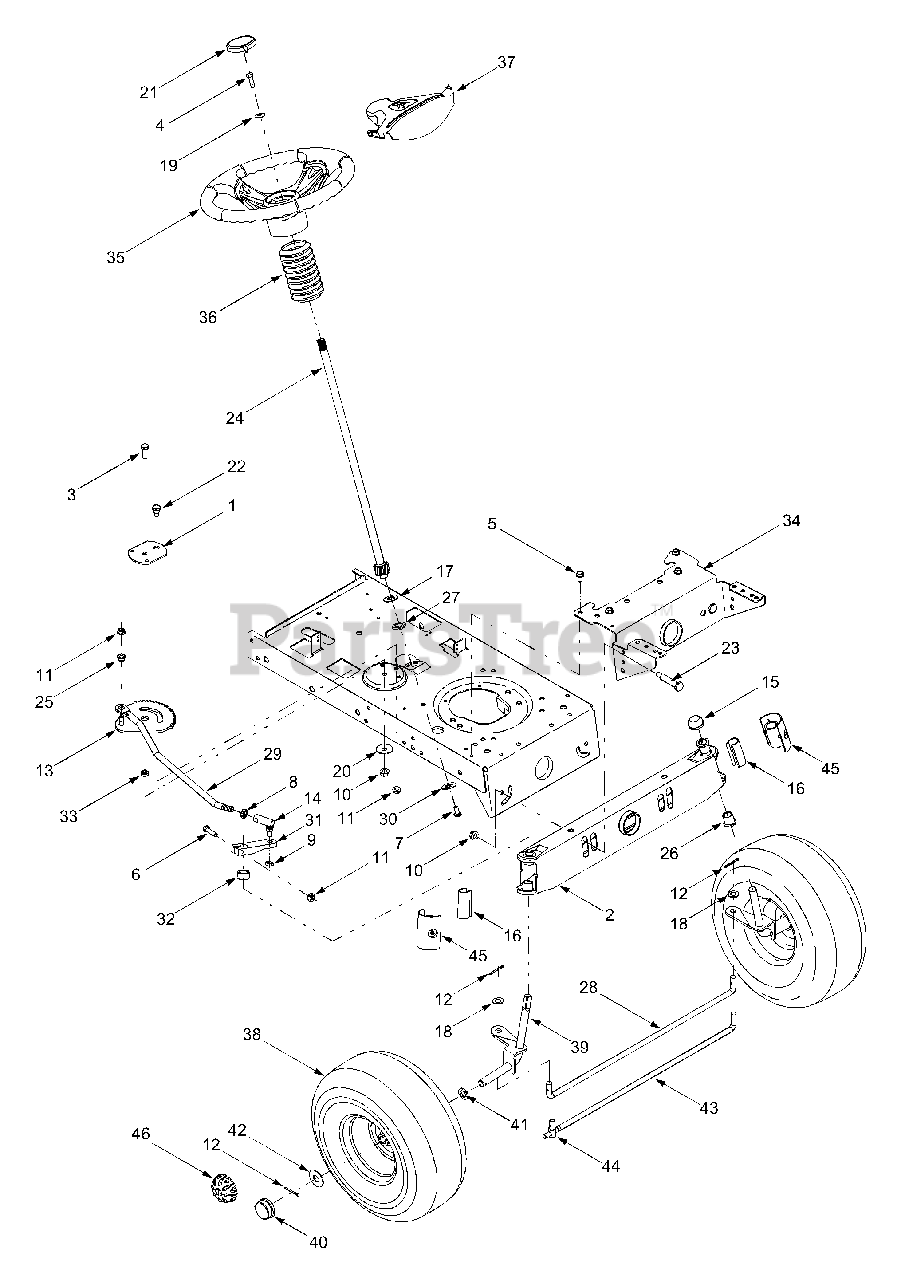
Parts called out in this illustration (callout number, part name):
1	Retainer Gear Segment Plate
4	Hex Cap Screw, 5/16-18 x 1.0
5	Self-tapping Screw, 5/16-12 x .75
6	Hex Cap Screw, 5/16-18 x 1.5
7	Machine Screw, 5/16-18 x .75
8	Jam Nut, 7/16-20 (Grade 2)
9	Jam Nut, 3/8-24
10	Flange Lock Nut, 3/8-16
11	Flange Lock Nut, 5/16-18
12	Cotter Pin, 1/8 x 1.25
13	Stearing Segment Gear
14	Ball Joint, 7/16 -20
15	Push Cap, .625
16	Axle End Cap, Standard
17	Flat Washer, .64 x 1.24 x .060
18	Flat Washer, .474 x .879 x .064
19	Bell Washer, .34 x .872 x .060
20	Bell Washer, .391 x .380 x .062
21	Steering Wheel Cap, Small
22	Shoulder Screw, .435 x .350, 5/16-18
23	Shoulder Screw, .498 x 2.045
24	Steering Shaft, 21.86
25	Plastic Bushing, .38 ID
26	Flange Buching, .632 ID
27	Hex Flange Bearing, 5/8
28	Tie Rod, Non-adjustable
29	Steering Drag Link, 7/16-20
30	Cap, 1.25 x .16
31	Steering Arm
32	Spacer, 1.0 x .645 x .56
33	Spacer, .380 x .625 x .21
35	Steering Wheel, Three Spoke
36	Steering Bellow, 4.75"
37	Steering Wheel Cap, Large
40	Hub Cap
41	Flat Washer, .64 x 1.0 x .12
42	Flat Washer, .635 x 1.589 x .06
43	Tie Rod, Adjustable
44	Ferrule, 3/8-24 x .437 Dia
45	Axle End Cap, w/ Fitting
46	Deluxe Hub Cap
